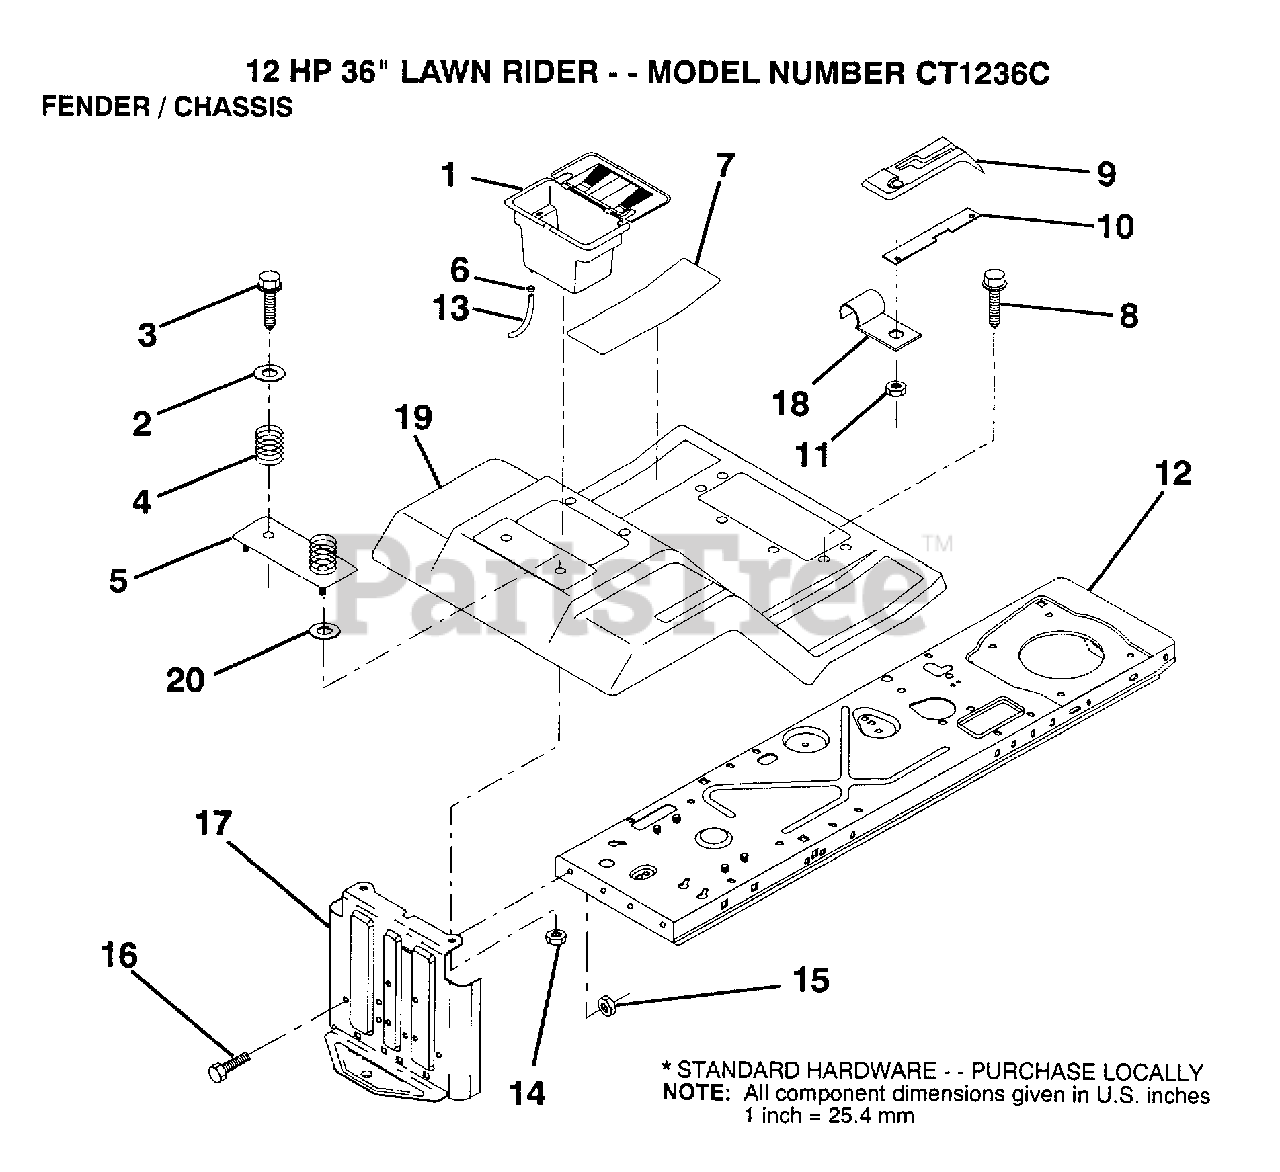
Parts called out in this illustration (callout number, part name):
2	WASHER
3	SCREW
4	SPRING COMPRESSIO
5	"PLATE, BATTERY"
6	HOSE CLAMP T
7	PAD FOOTREST
8	SCREW
10	"SHIFT LOCK, BAR"
11	NUT
12	FRAME ASS'Y
14	NUT
16	BOLT
17	DRAWBAR
18	"CLIP,INSULATOR"
